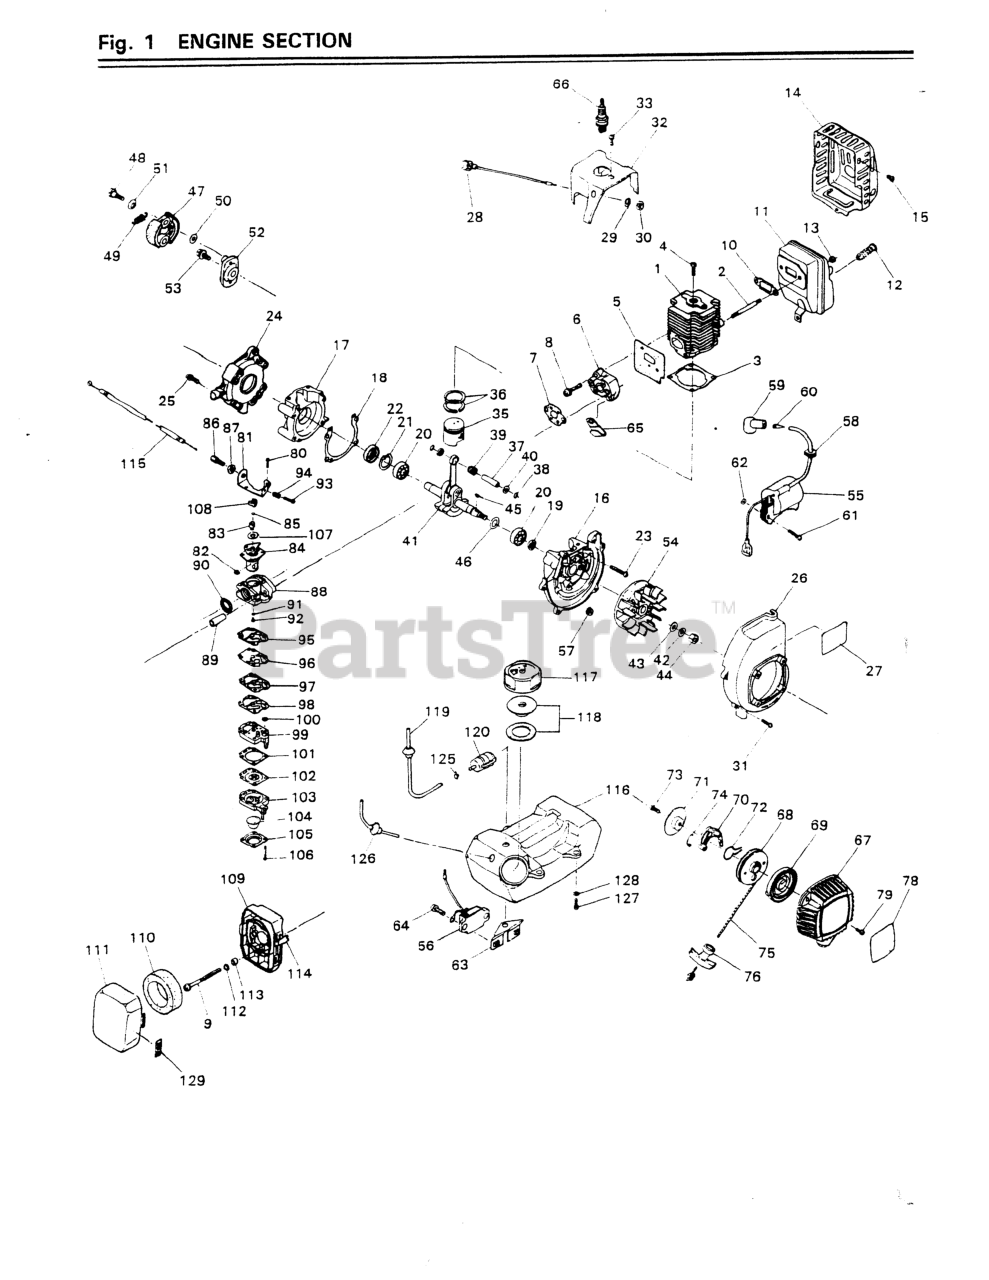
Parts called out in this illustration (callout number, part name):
1	CYLINDER-C
2	STUD
4	SCREW, M5 X 16
6	INSULATOR
12	ARRESTER (RPLS 5850-15140)
13	NUT
16	CRANKCASE (RPLS -21100)
17	CRANKCASE (RPLS -21100)
19	SEAL, OIL
20	BEARING
21	RING, SNAP, M28 x 1.2
22	SEAL, OIL (RPLS 1140-21220)
23	SCREW, M5 x 30(RPLS 0263-00530
24	CASE, CLUTCH
26	COVER COMP
29	WASHER
30	NUT
31	SCREW, M4 x 14
32	COVER, CYLINDER
35	PISTON (USE 5600-41111)
36	RING, PISTON (RPLS 1850-41210)
37	PIN, PISTON 5x8x26
38	RING, SNAP (RPLS 1101-41320)
40	WASHER
42	WASHER, M8 x 20
43	WASHER, M8 x 1.2
45	KEY
48	BOLT
50	WASHER, FLAT (USE 182303)
53	BOLT, M6 x 14(RPLS 0224-00614)
56	UNIT
60	SPRING
61	SCREW, M4 x 20
62	WASHER, M5 X .8
64	SCREW, M5 X 12
65	CLAMP
66	SPARK PLUG
67	STARTER ASSEMBLY
70	RATCHET
71	PLATE (NLA) (RPLS -75240)
72	SPRING, FRICTION
73	SCREW (USE -75261)
74	SPRING
76	KNOB
79	SCREW, M4 X 12
80	SCREW
81	BRACKET, IDLE
82	RING
83	SWIVEL (USE -06040)
84	VALVE, THROTTLE
85	PLUG NEEDLE
87	NUT, CABLE ADJUSTER
88	CARBURETOR-A (NLA)
89	SLEEVE, MOUNT
90	RING, PACKING (NLA)
91	RING, O
93	SCREW, IDLE AD
94	SPRING, IDLE A
95	GASKET, PUMP
96	DIAPHRAGM
97	PLATE, PUMP (NLA)
98	GASKET, PLATE
99	KIT ONLY
100	SCREEN
101	KIT ONLY
102	DIAPHRAGM (USE 4810-81260)
103	BODY
104	PUMP, PRIMING
105	COVER
106	SCREW
107	WASHER
108	CAP, CABLE END
109	CLEANER ASSEMBLY
111	CLEANER ASSEMBLY
113	SLEEVE (USE 1918-82170)
118	VALVE COMPLETE
119	PIPE COMP
120	5500-85400 (RRLS. 1750-85300)
125	CLIP (REPLACES 2841-31280)
127	SCREW, M5 X 16
128	WASHER, M5x.8(RPLS 01624-20508
129	LABEL
NI	CYLINDER-C
NI	MUFFLER ASSEMBLY
NI	CRANKCASE (RPLS -21100)
NI	COVER COMP
NI	STARTER ASSEMBLY
NI	CARBURETOR-A (NLA)
NI	CLEANER ASSEMBLY
